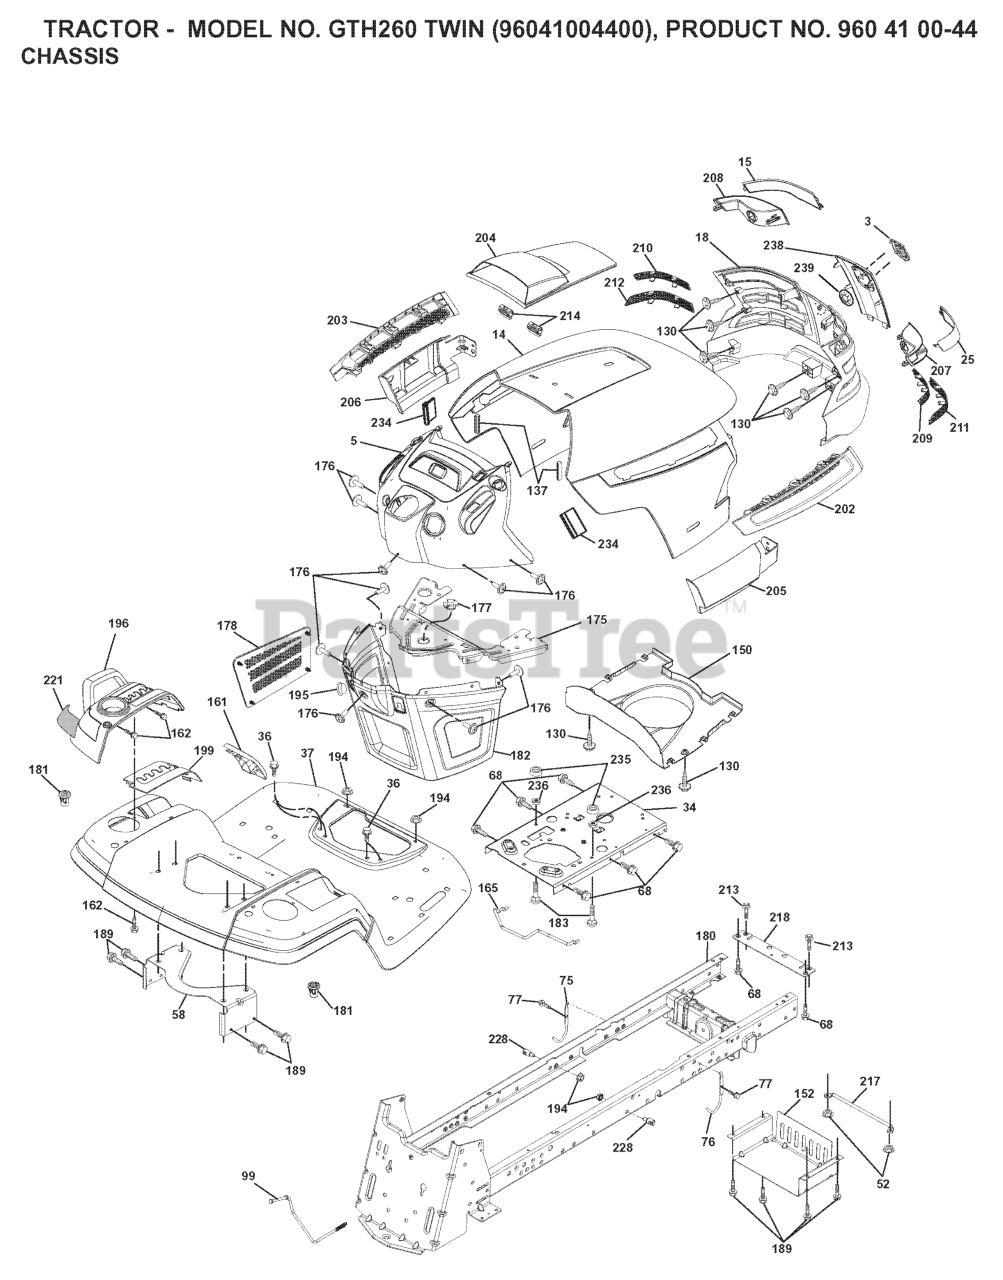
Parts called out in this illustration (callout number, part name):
3	RP LOGO
5	DASH.ASM.HUSQ.GT.E.RECT.W/CK
14	HOOD
15	LENS.LH.TEX.GT.HUSQ.CL
18	GRILL.ASM.HUSQ.TG/CRD.W/TRIM
25	LENS.RH.TEX.GT.HUSQ.CL
34	PLATE.ENGINE.WELDED.CHASSIS
36	SCREW 5/16"
37	FENDER.PNT.TX.GT.CH/FW.ORANGE
52	LOCKNUT
58	BRKT.SUPPORT.FNDR/TANK
68	Screw 5/16-18 x 1/2 Hex, Self Tapping 5/16-18 x 1/2
75	ROD UPSTOP
76	ROD UPSTOP
77	SCREW 3/8-16X1
99	ROD BYPASS ASM.
130	SCREW
137	BUMPER DASH
150	AIR.DUCT.HOOD.TEX.GT.HUSQ
152	SHIELD.BROWNING.W/TEX
161	CONSOLE.FUEL.WINDOW.HU
162	SCREW.HI-LO.CONSOLE
165	SUPPORT.TANK.REAR.W/TEX
175	PLATE.CROSSMEMBER.HUSQ
176	SCREW.#10-24X5/8.RN.QU
177	BUSHING, STEERING
178	CARGO.ASM.NET.TXGT.W/C
180	CHASSIS.GT.SLOPED.DRAWBAR.
181	BUSHING.MNT.FEND.CRGO.
182	DASH.LOWER.COMMON.12V.
183	BOLT.5/16-18X1-1/4 FULL.THREAD
189	SCREW
194	NUT LOCK HEX FLANGE 5/16-18
195	PLUG.HOLE.DASH.LOWER.12V.BLK
196	RP CONSOLE.ASM.DECKLFT.W/
199	PLATE.DECK.LIFT.HUSQVARNA.GT
202	VENT.SIDE.HOOD.HUSQ.RH.GREY
203	VENT.SIDE.HOOD.HUSQ.LH.GRAY
204	VENT.TOP.HOOD.HUSQVARN
205	SKIRT.HOOD.SIDE.HUSQ.RH.GREY
206	SKIRT.HOOD.SIDE.HUSQ.LH.GREY
207	BEZEL.RH.TEX.GT.HUSQ
208	BEZEL.LH.TEX.GT.HUSQ
209	INSERT.HEX.GRILL.HUSQ.GREY
210	INSERT.HEX.GRILL.HUSQ.
211	INSERT.HEX.GRILL.HUSQ.
212	INSERT.HEX.GRILL.HUSQ.
213	BOLT
214	CLIP.RETAINER.TINNER.
217	ROD PIVOT CHASSIS/HOOD
218	X-PIECE.HOOD.STOP.NON/
221	REFLECTOR.LH.TEX GT HU
228	STUD.FASTNER.W/ANTI-ROTATE
234	BUMPER.HOOD.TEX.HUSQVARNA
235	SPACER FENDER
236	NUT.CENTERLOCK.5/16-
238	TRIM.HUSQ.TG/CRD.SERVICE
239	NUT PUSH M
